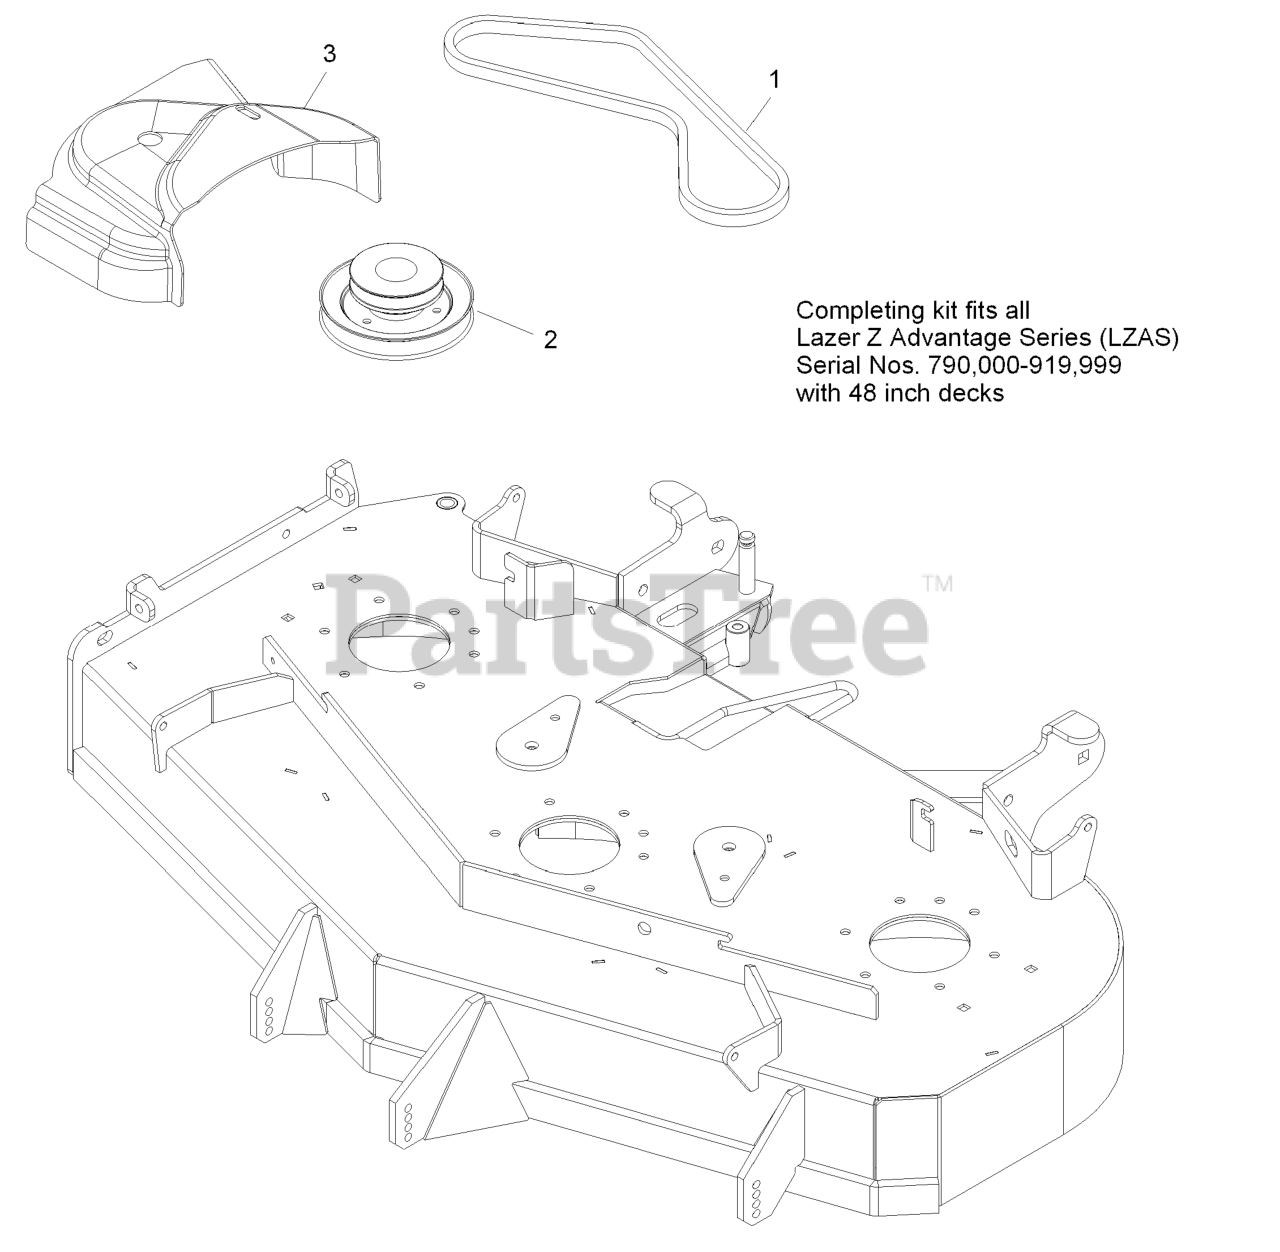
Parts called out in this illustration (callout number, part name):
1	Belt, Blower (48")
2	Jackshaft,Uv Drive 484
3	Cover,Belt Uv 48
